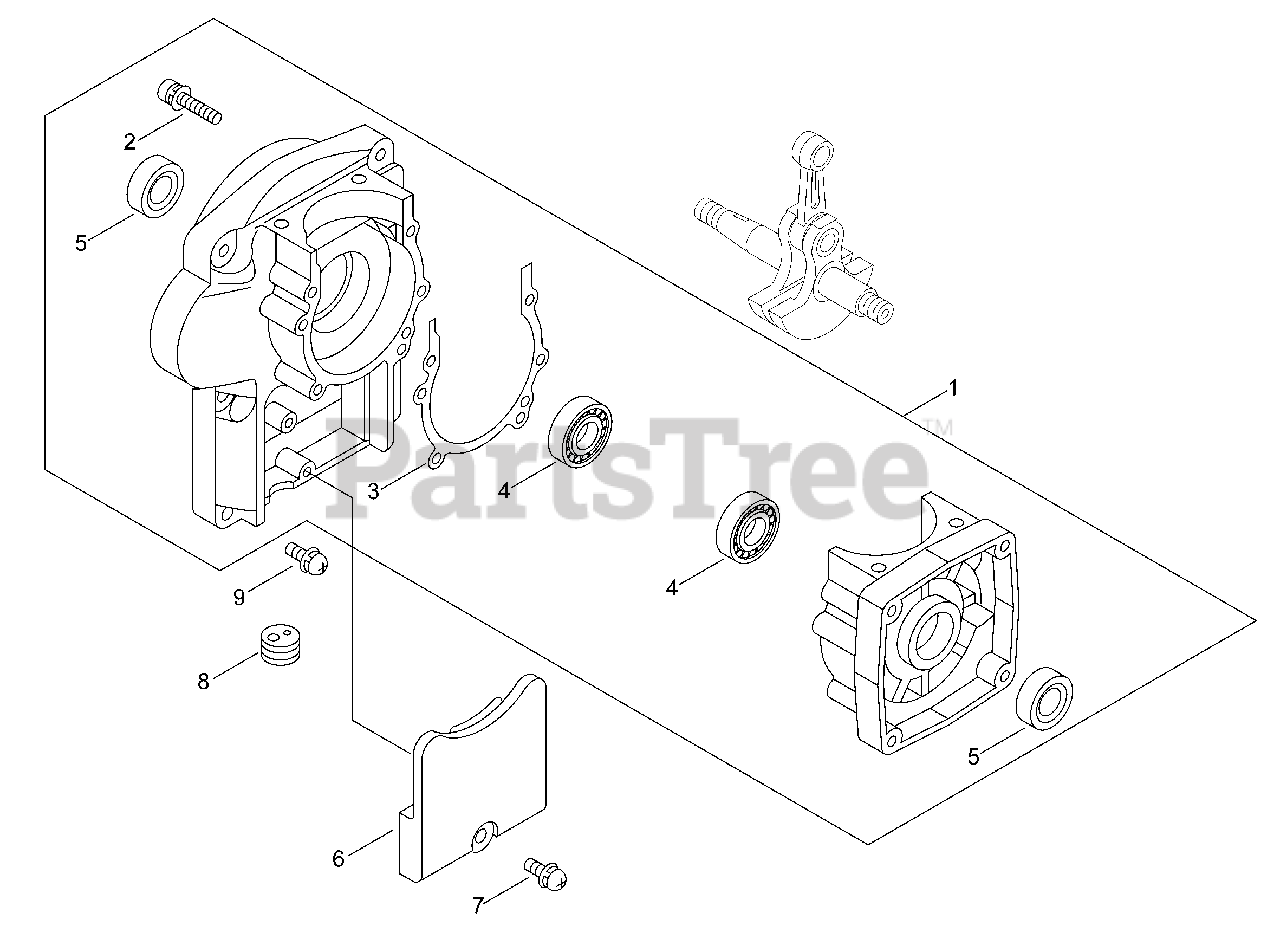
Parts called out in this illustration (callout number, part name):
1	CRANKCASE KIT
2	BOLT 5×40
3	GASKET, CRANKCASE
4	BEARING, BALL 6202
5	SEAL, OIL
6	COVER, DUST
7	SCREW 5×18
9	SCREW 5×25 SUS
